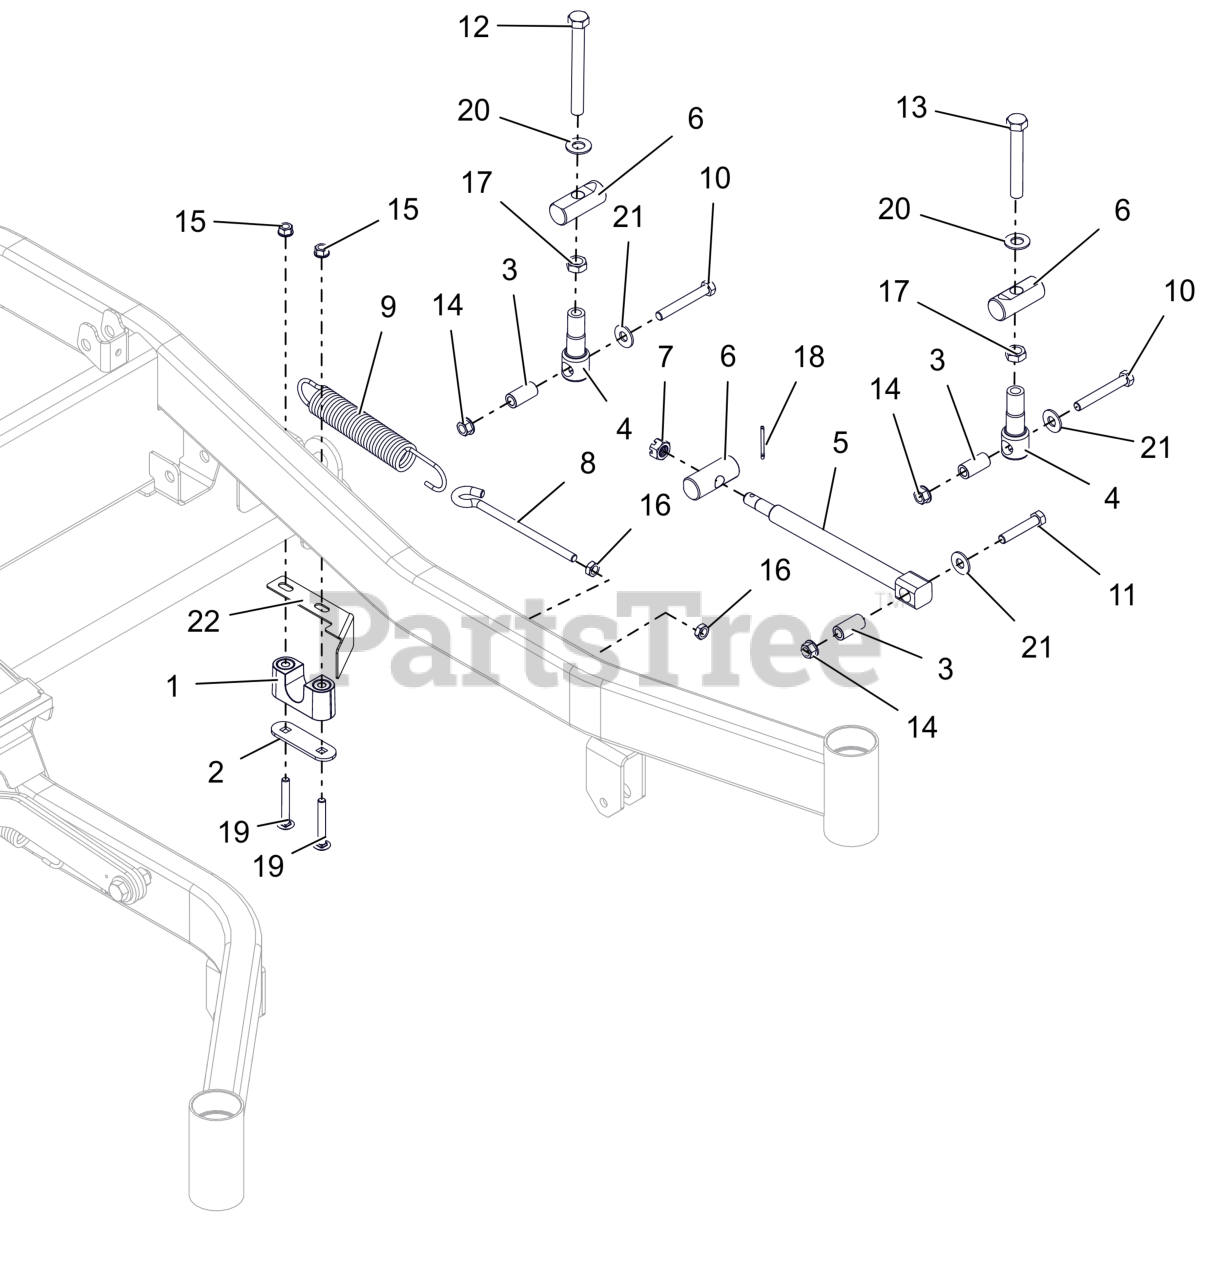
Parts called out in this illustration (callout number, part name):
1	ASM-BUSHING, DECK LIFT
2	PLATE, BEARING SUPPORT
3	SPACER, DECK LEVELING
4	LINK, DECK LIFT FORMED
5	DRAG,LINK-HD
6	PIN, DECK LIFT
7	NUT-SL .50-13
8	BOLT,.38-16 X 5.25-.62 DIA EYE
9	SG-TENS .162X1.25X8.25 WLD 25
10	BLT, HEX .38-16X2.75 G8 ZCC
11	BLT,HEX .38-16X2.00 G5 ZCC
12	BLT, HEX .50-13X4.50F G8 ZCC
13	BLT, HEX .50-13X3.50F G5 ZCC
14	NUT-LK-TOP-FLG .38-16 ZC120
15	NUT,LK-CTR-FLG .31-18 GF ZCC
16	NUT-JAM .375-16 G2 ZCC
17	NUT-JAM .500-13 G2 ZCC
18	PIN,CTR.12X1.25EXTPRSQCT ZC120
19	BLT, RHSSN.31-18X2.25 G5 ZCC
20	WSHR, FLT .557X1.040X.102 ZCC
21	WSHR,FLT .438X1.00X.083 ZCC
22	GUARD, STOP CE 60 (BLACK)
